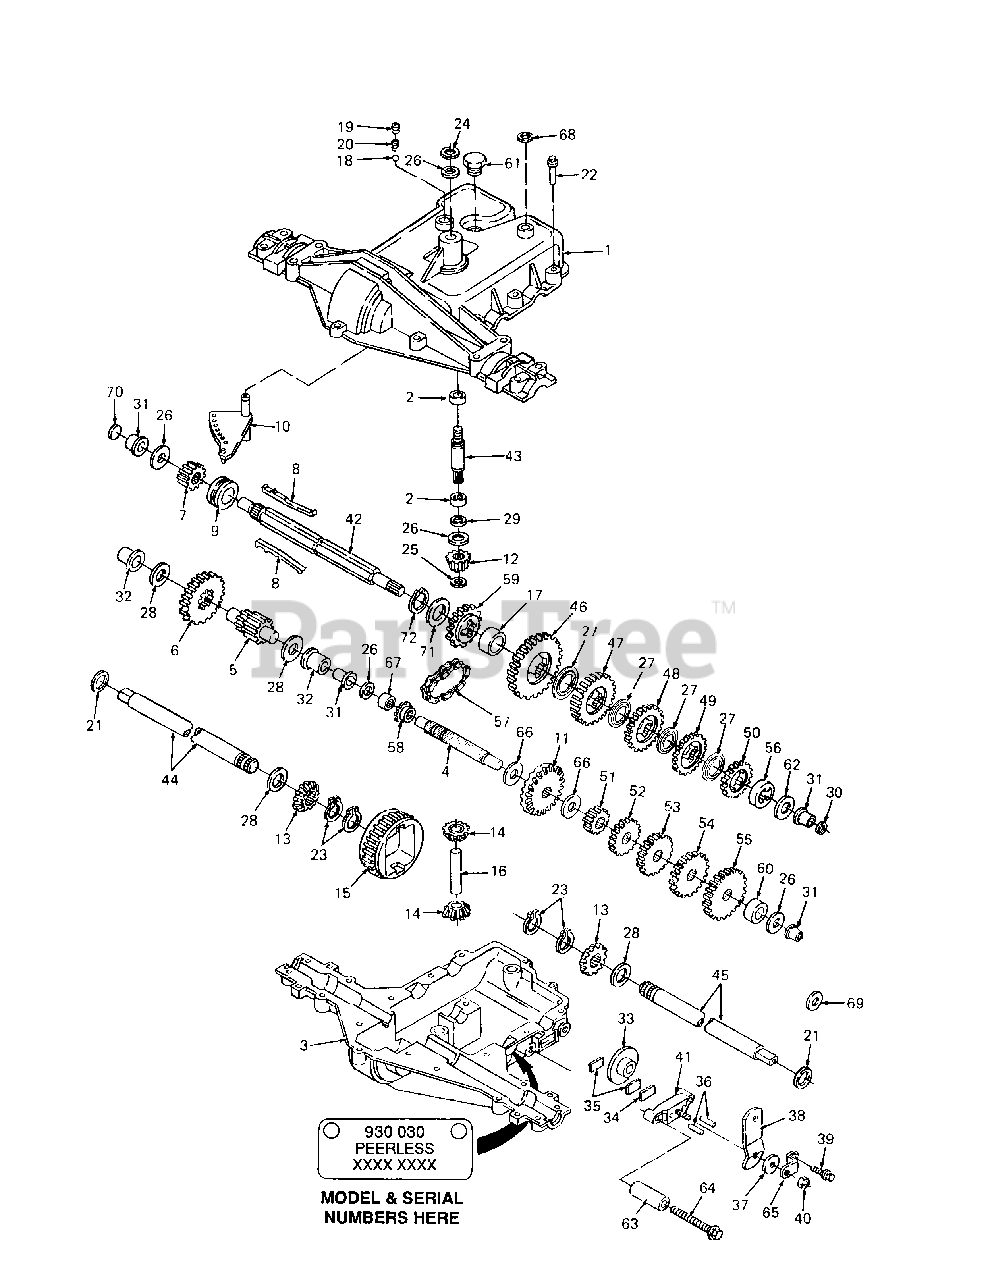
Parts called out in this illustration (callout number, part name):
1	Cover, Transaxle
2	Bearing, Needle
3	Case, Transaxle
4	Shaft, Counter
5	Shaft & Pinion Assy, Output
6	Gear, Output
7	Gear, Spur (1 5 Teeth)
8	Key, Shitter
9	Collar, Shifter
10	Rod & Fork Assy, Shift
11	Gear, Bevel (42 Teeth)
12	Gear, Bevel Input
13	Gear, Bevel
14	Gear, Bevel Pinion
15	Gear, Ring
16	Pin, Drive
18	Ball, 5/16 Dia, Grade 200
21	Ring, Seal
22	Screw, Flanged Hex, 1/4-20 X 1.25 Lg
23	Ring, Retainer (Set of 2)
24	Ring, Retaining
25	Ring, Ext Ret, .521
26	Washer, Thrust
29	Ring, Ouad
30	Ring, Sq Cut
31	Bushing, Flanged
33	Brake, Disc
34	Plate, Brake Pad
35	Pad, Brake
36	Pin, Dowel
37	Washer, Flat, .344 X 1.0 X.063 HDN
38	Lever, Brake
39	Screw, Flanged Hex, 1/4-20 X 1.25 Lg
40	Nut
41	Holder, Brake Pad
42	Shaft, Brake (4-Keyed)
43	Shaft, Input
44	Axle, 11.62 Lg
45	Axle, 16.0 Lg
46	Gear, Spur (37 Teeth)
47	Gear, Spur (30 Teeth)
48	Gear, Spur (25 Teeth)
49	Gear, Spur (22 Teeth)
50	Gear, Spur (20 Teeth)
51	Gear, Spur (12 Teeth)
52	Gear, Spur (20 Teeth)
53	Gear, Spur (25 Teeth)
54	Gear, Spur (28 Teeth)
55	Gear, Spur (30 Teeth)
57	Chain, Roller
58	Sprocket (9 Teeth)
59	Sprocket (1 8 Teeth)
62	Washer, Thrust
64	Screw, Hex Flanged Hd 1/4-20 X 2-1/4 Lg
65	Bracket, Brake Lever
66	Washer, Thrust
68	Seal, Sq Cut
70	Disk
71	Washer, Thrust
72	Ring, Retaining
